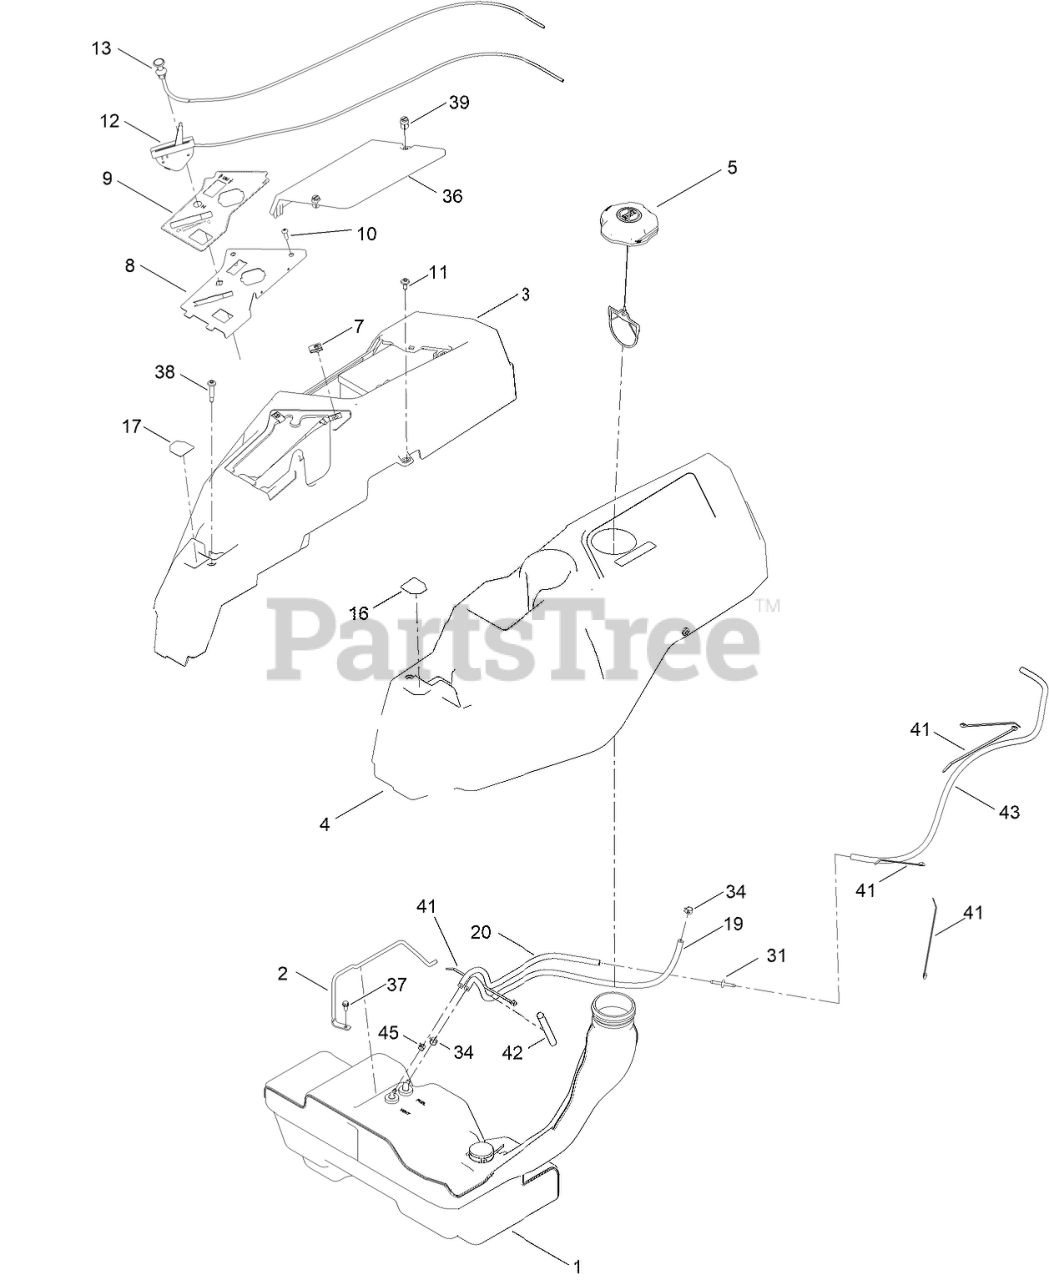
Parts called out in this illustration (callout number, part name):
1	TANK-FUEL ASM
2	ROD-HOLD DOWN
3	POD-RH
4	POD-LH
5	CAP-FUEL, RATCHETING
8	PANEL-CONTROL
9	DECAL-PANEL, CONTROL
10	SCREW-PRH
11	SCREW-SHOULDER
12	CABLE-THROTTLE
13	CABLE-CHOKE
16	DECAL-LEVER, CONTROL (LH)
17	DECAL-LEVER, CONTROL (RH)
19	HOSE-FUEL
20	HOSE-VENT
31	ADAPTER ORIFICE
34	CLAMP-HOSE
36	COVER-BATTERY
37	SCREW-HWH
38	SCREW-SHOULDER
39	FASTENER
41	TIE-CABLE
42	SLEEVE-FUEL LINE PROTECTOR
45	CLAMP-HOSE
